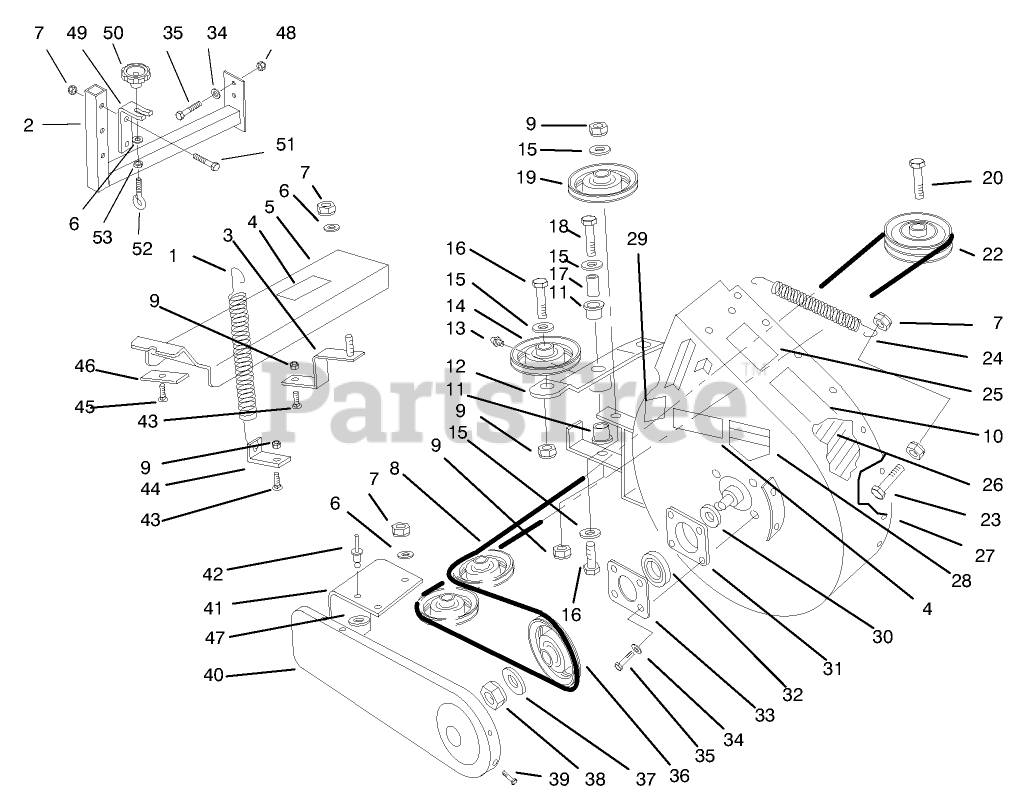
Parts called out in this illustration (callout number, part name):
1	SPRING-EXTENSION
2	WA - BRACKET
3	Bracket
4	DECAL-DANGER
5	ASM - BELT CVR W/DECAL B
6	WASHER-PLAIN
7	NUT-LOCK, NI
8	V-BELT
9	NUT-LOCK, NI
10	DECAL - WARNING
11	BUSHING
12	ARM-IDLER-WELDED B
13	FITTING-GREASE
14	PULLEY-IDLER, FLAT
15	WASHER-FLAT
16	SCREW-HH
17	SPACER
18	SCREW-HH
19	PULLEY-IDLER
20	SCREW-HH
22	PULLEY
23	SCREW-HH
24	SPRING - EXTENSION
25	DECAL-DANGER
26	STRIP-WEAR
27	ASM - BLOWER W/DECALS B
28	DECAL-DANGER
29	Decal
30	SPACER-BEARING
31	CUP-BEARING
32	BEARING-BALL
33	Cover-Plate
34	WASHER-LOCK
35	SCREW-HH
36	PULLEY-BLOWER R
37	WASHER-FLAT
38	NUT 5/8-11 L.H.
39	SCREW
40	SHIELD-PULLEY B
41	SHIELD
42	RIVET-BLIND
43	BOLT-CARR
44	BRACKET-ANGLE B
45	SCREW-CARR
46	STRAP B
47	WASHER-FLAT
48	NUT-LOCK, NI
49	PLATE - SUPPORT
51	SCREW-HH
52	BOLT-EYE
53	NUT-HEX
